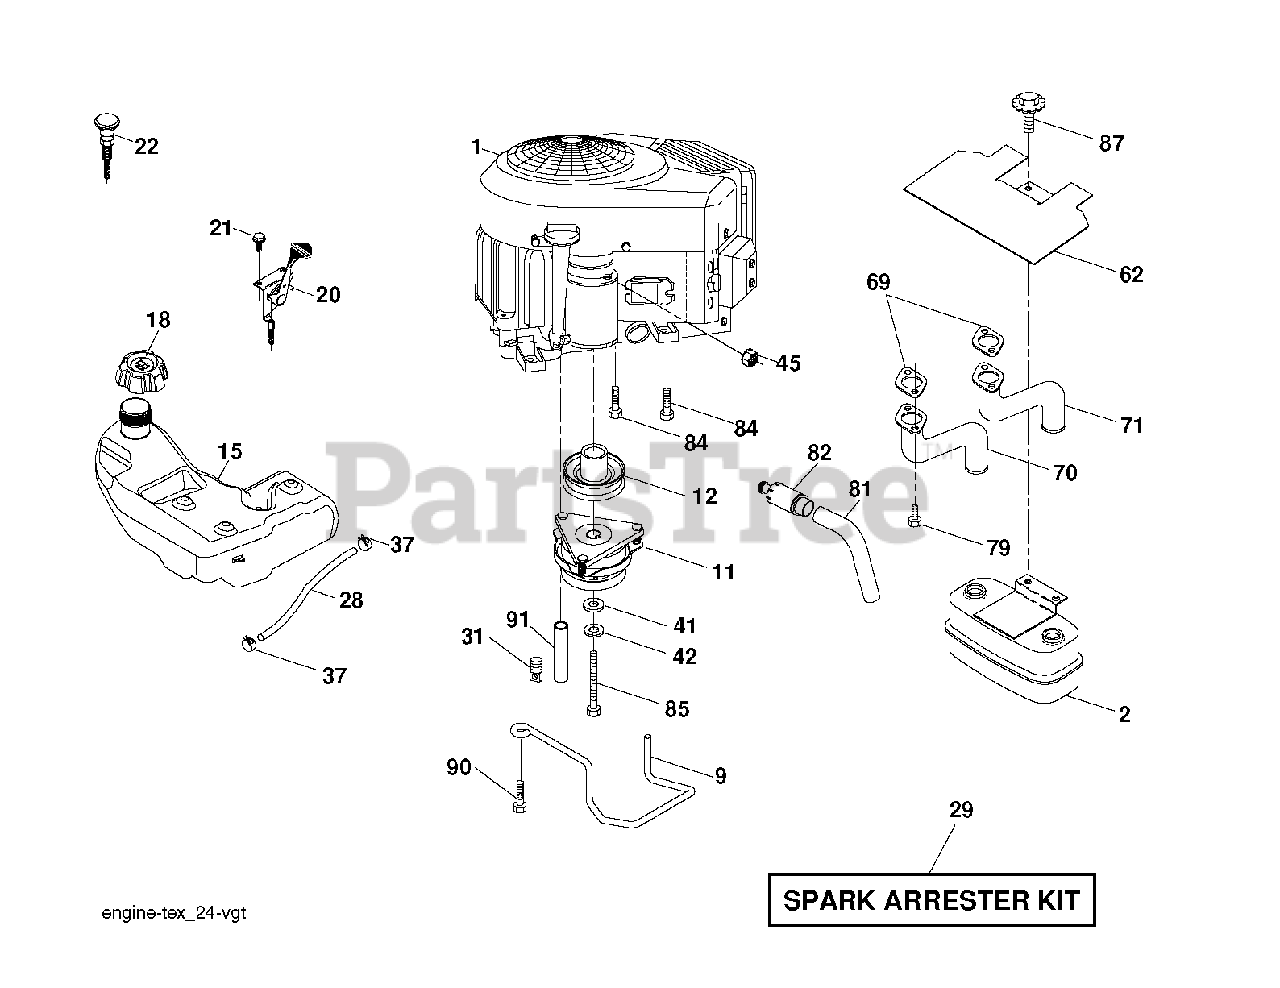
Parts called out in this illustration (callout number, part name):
2	MUFFLER.TWIN.CYL.LOW.TONE
9	KEEPER.BELT.ENGINE.4.2
11	CLUTCH ELECTRIC
12	PULLEY ENGINE
15	TANK.FUEL.4GAL
18	CAP.ASM.FUEL.TANK.3"BL
20	THROTTLE CABLE
21	SCREW
22	CONTROL CHOKE
29	ARRESTER SPARK (OPTIONAL)
31	PUSH CLIP
37	HOSE CLAMP
42	LOCKWASHER
45	NUT
62	RP SHIELD HEAT MUFFLER
69	GASKET.MUFFLER
70	TUBE MANIFOLD LH
71	EXHAUST TUBE RH
79	SCREW.SOCKET.HEAD.5/16-18
81	TUBE, DRAIN OIL ASM.
82	PLUG DRAIN OIL EASY
84	SCREW.3/8-16
85	BOLT HEX 7/16-20 X 3.75 GR. 5
87	BOLT.5/16-18UNCX1.W/SEMS.BLK
90	SCREW 3/8-16X1
91	BUSHING.1.375OD
